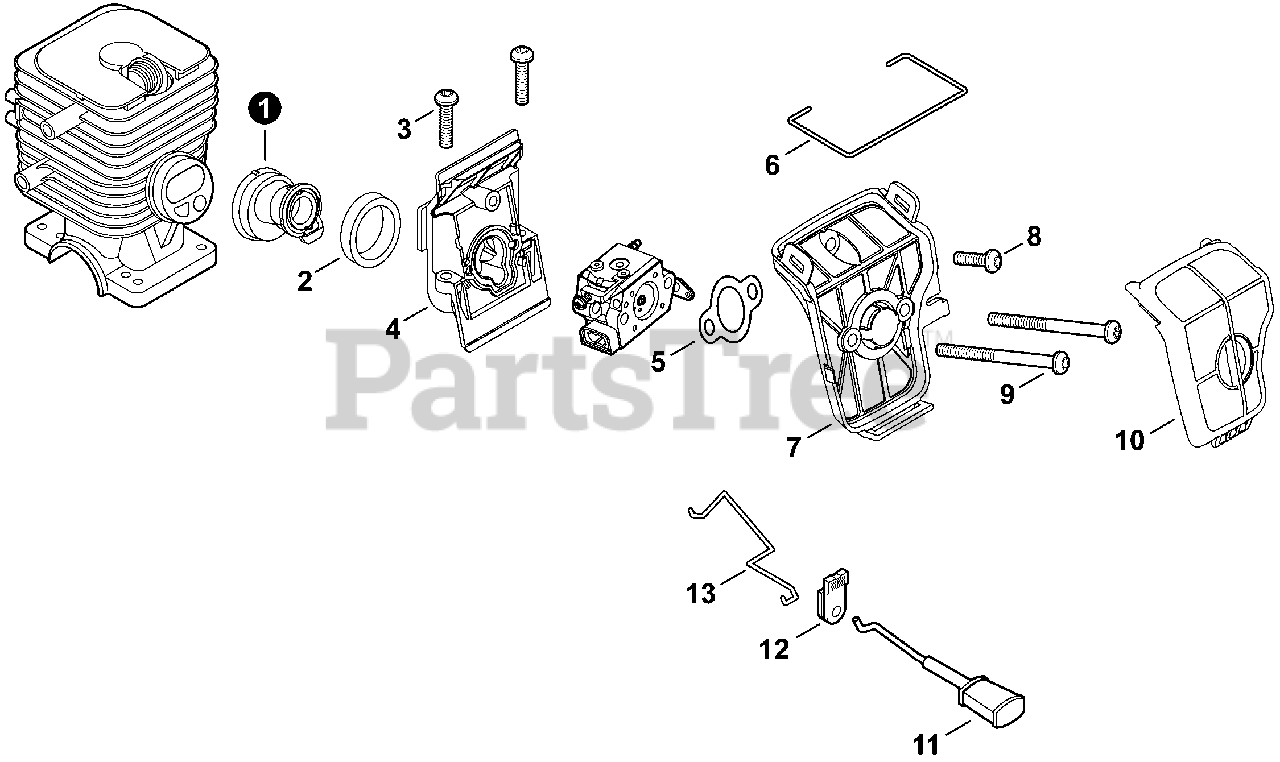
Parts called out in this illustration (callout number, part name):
1	BELLOWS, INTAKE
2	RETAINER, BELLOWS
3	BOLT, TORX 5×20
4	INSULATOR, INTAKE
5	GASKET, INTAKE
6	RETAINER, AIR FILTER
7	CASE, AIR FILTER
8	BOLT, TORX 5×16
9	BOLT, TORX 5×55
10	FILTER, AIR
11	ROD, CHOKE
12	GROMMET, CHOKE
13	ROD, THROTTLE
